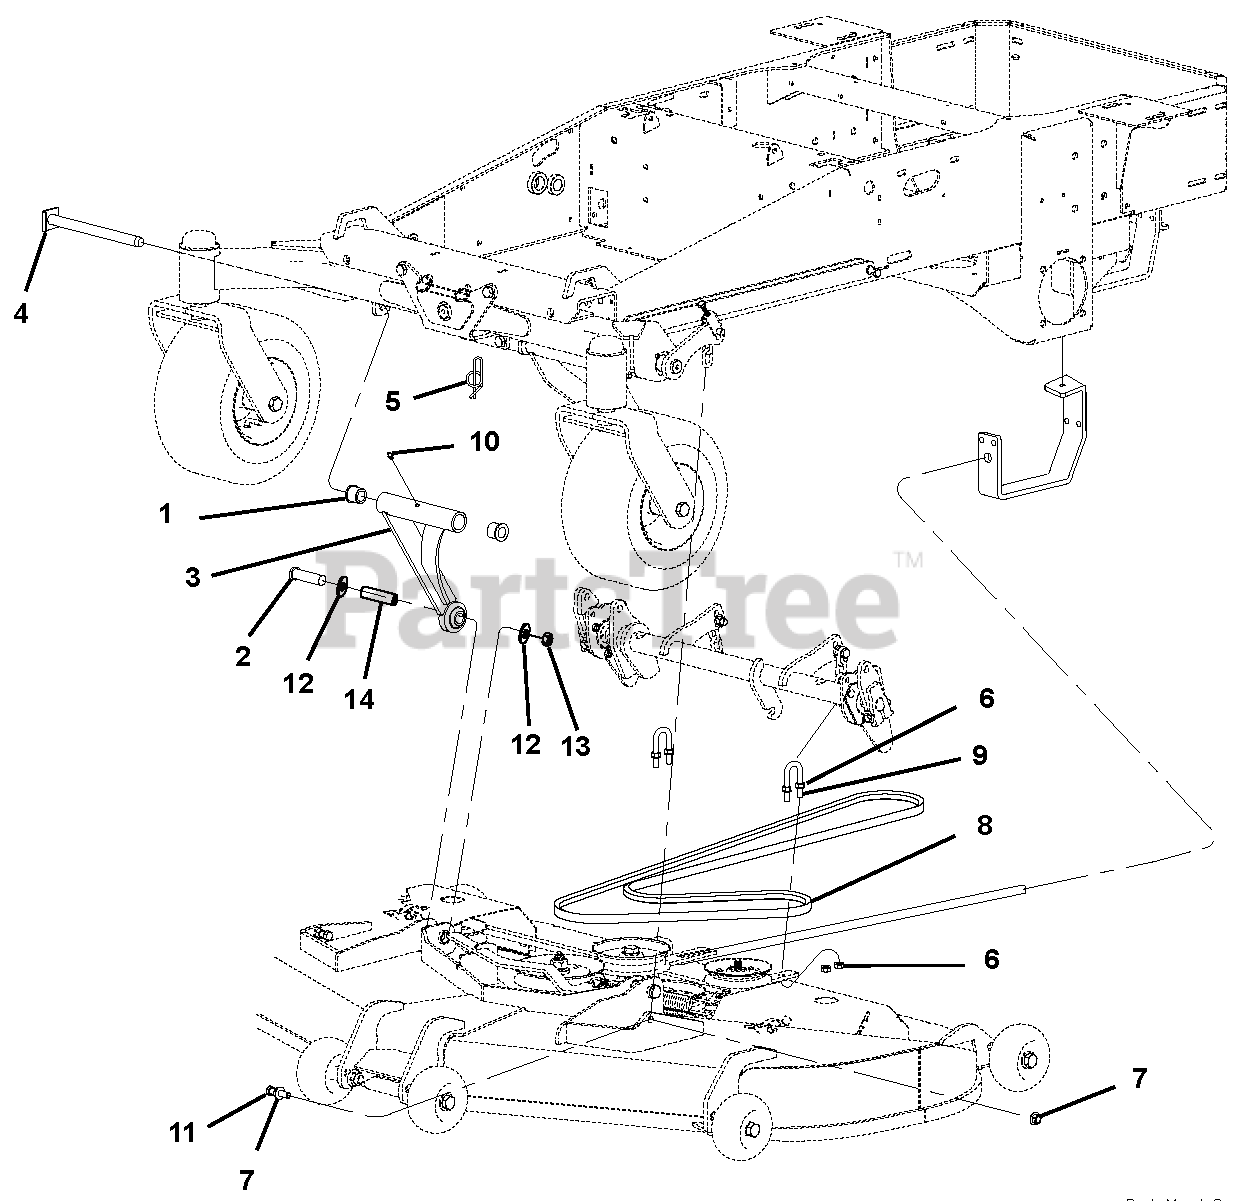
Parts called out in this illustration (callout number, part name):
1	Bushing, 3/4 I.D.
2	Bolt, .50-13 x 3.50 Hex 5
3	Weldment, Deck Pull 11.5
4	Weldment, Drag Link Pin
5	Ring, Rue .750 x .080 x 2.081
6	Nut, Spin Lock, Flange .375-16
7	Locknut, 7/16-14 Whiz
8	Belt, B112 Kevlar (Clutch to Deck)
9	U-Bolt Special
10	Fitting, 1/4-28 Straight Grease Zerk
11	Bolt, 7/16-14 x 1-3/4
12	Washer, Flat, Steel .563 x 1.38 x .109
13	Nut, Locking, Cone
14	Tube, RD .750 x .125W x 2.469
